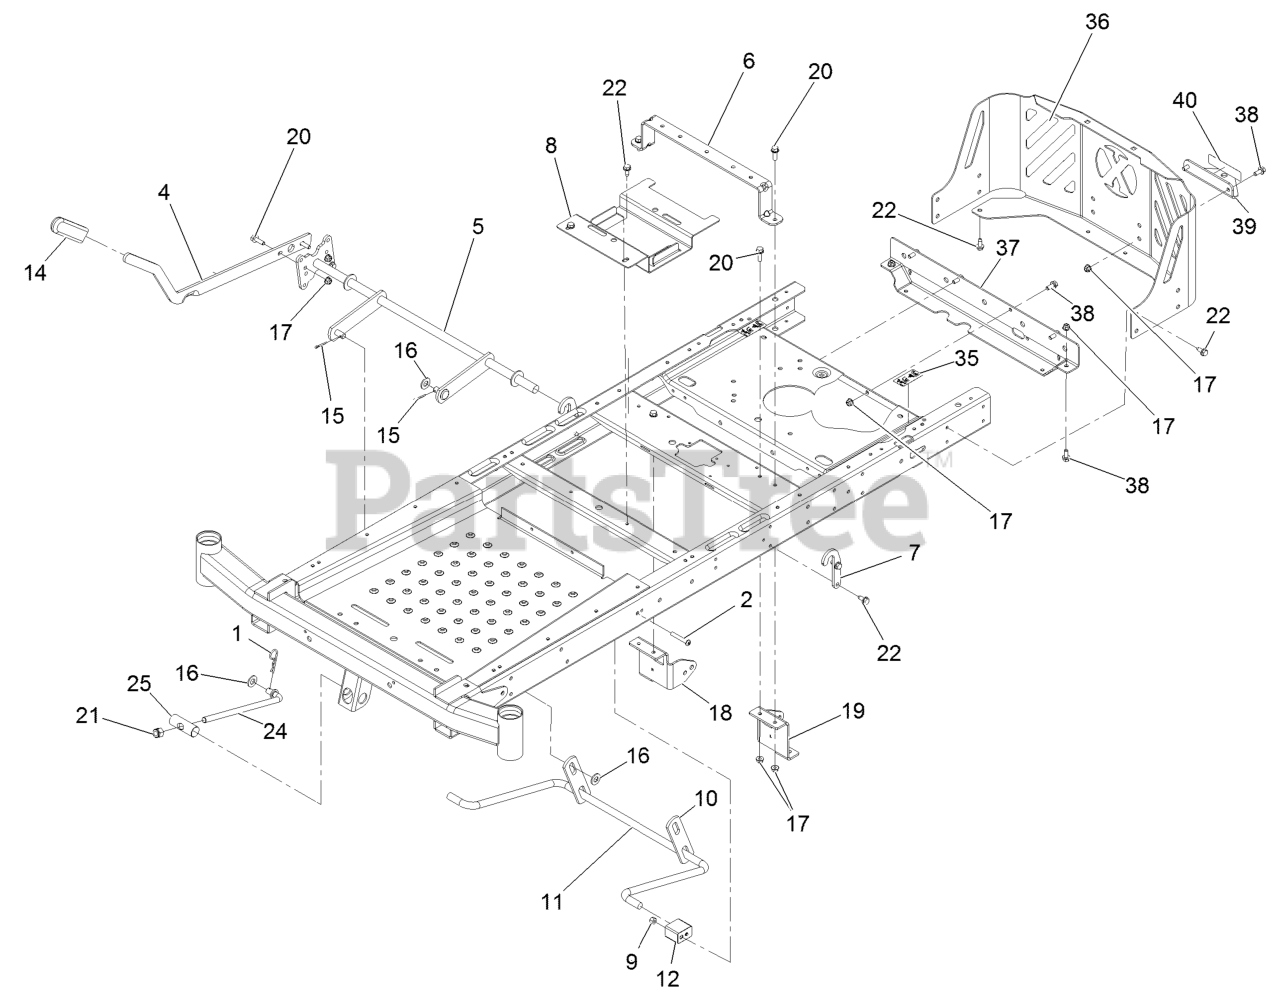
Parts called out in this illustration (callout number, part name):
1	PIN-COTTER
2	SCREW-HSBH
4	LEVER-LIFT
6	BRACE-SEAT, REAR
7	BRACKET-LIFT
8	BRACKET-BATTERY
9	NUT-LOCK, NI
10	LINK-LIFT
11	ARM-LIFT, REAR (WIDE)
12	BLOCK-PIVOT
14	GRIP-LEVER
15	PIN-COTTER
16	WASHER-FLAT
17	NUT-HF, NI
18	MOUNT-HYDRO, FRONT (RH)
19	MOUNT-HYDRO, FRONT (LH)
20	SCREW-HHF
21	NUT-HEX
22	Screw-HWH 5/16-18 X 3/4 Tf
24	ROD-MOUNT, DECK
25	PIN-PIVOT
35	DECAL-BYPASS
36	GUARD-ENGINE, WIDE
37	CROSSMEMBER-REAR, WIDE
38	SCREW-HHF
39	BRACKET-HITCH
